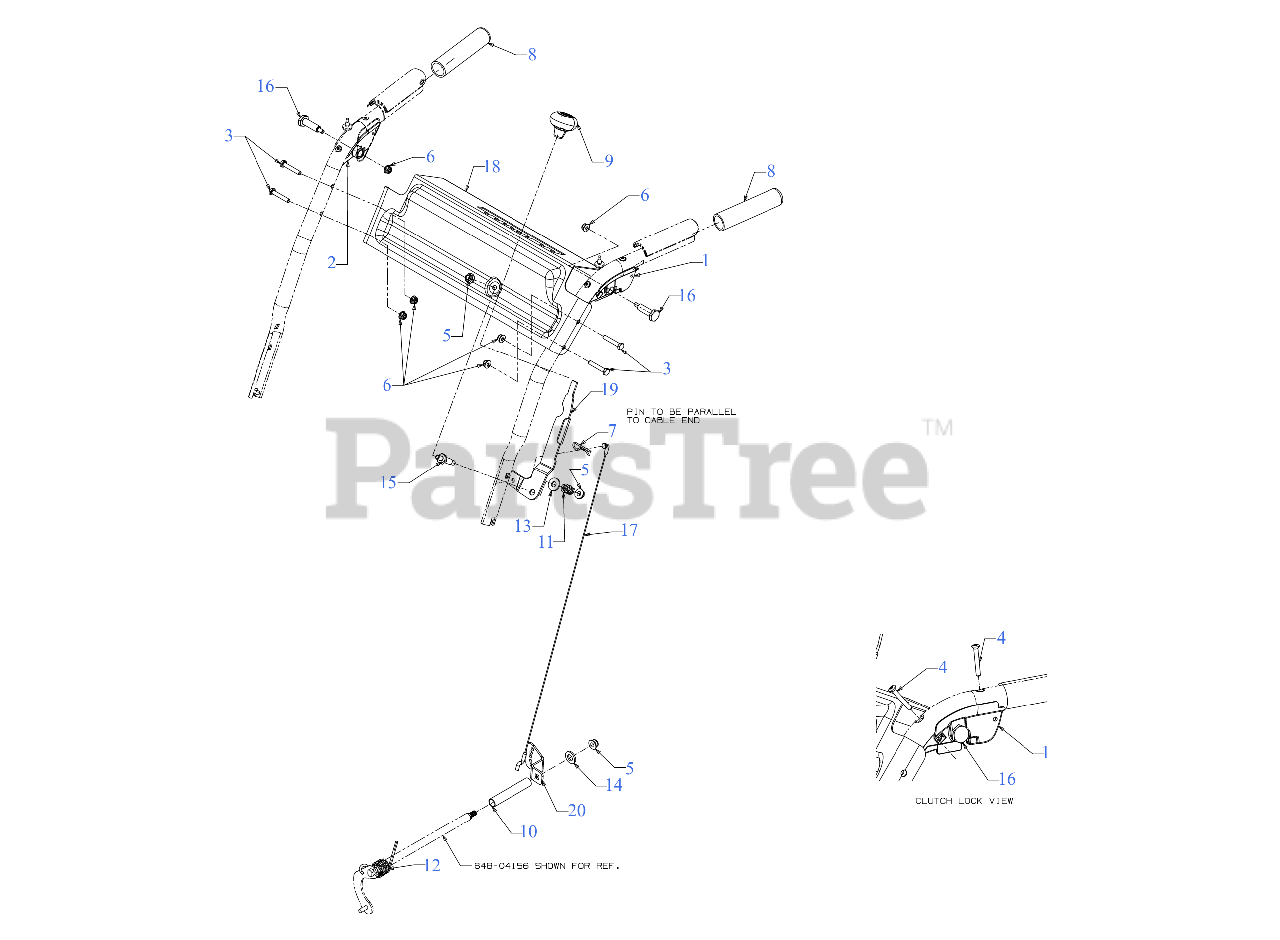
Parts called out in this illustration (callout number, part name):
1	CLUTCH LOCK HANDLE ASSEMBLY (LH)
2	CLUTCH LOCK HANDLE ASSEMBLY (RH)
3	SCREW 1/4-20 x 1.50 GR.5
4	SCREW #10-24 x 1.375
5	FLANGE LOCK NUT 5/16-18
6	FLANGE LOCK NUT
7	INTERNAL COTTER PIN
9	SHIFT KNOB
10	COVER .505 X .635 X 3.64
11	COMPRESSION SPRING
12	TORSION SPRING
13	FLAT WASHER .385X.870X.090
14	FLAT WASHER
15	SHOULDER BOLT
16	SHOULDER SCREW .437 x 1.345 1/4-20
17	SPEED SELECTOR CABLE (STEEL)
20	SPEED SELECT SHIFT BRACKET
